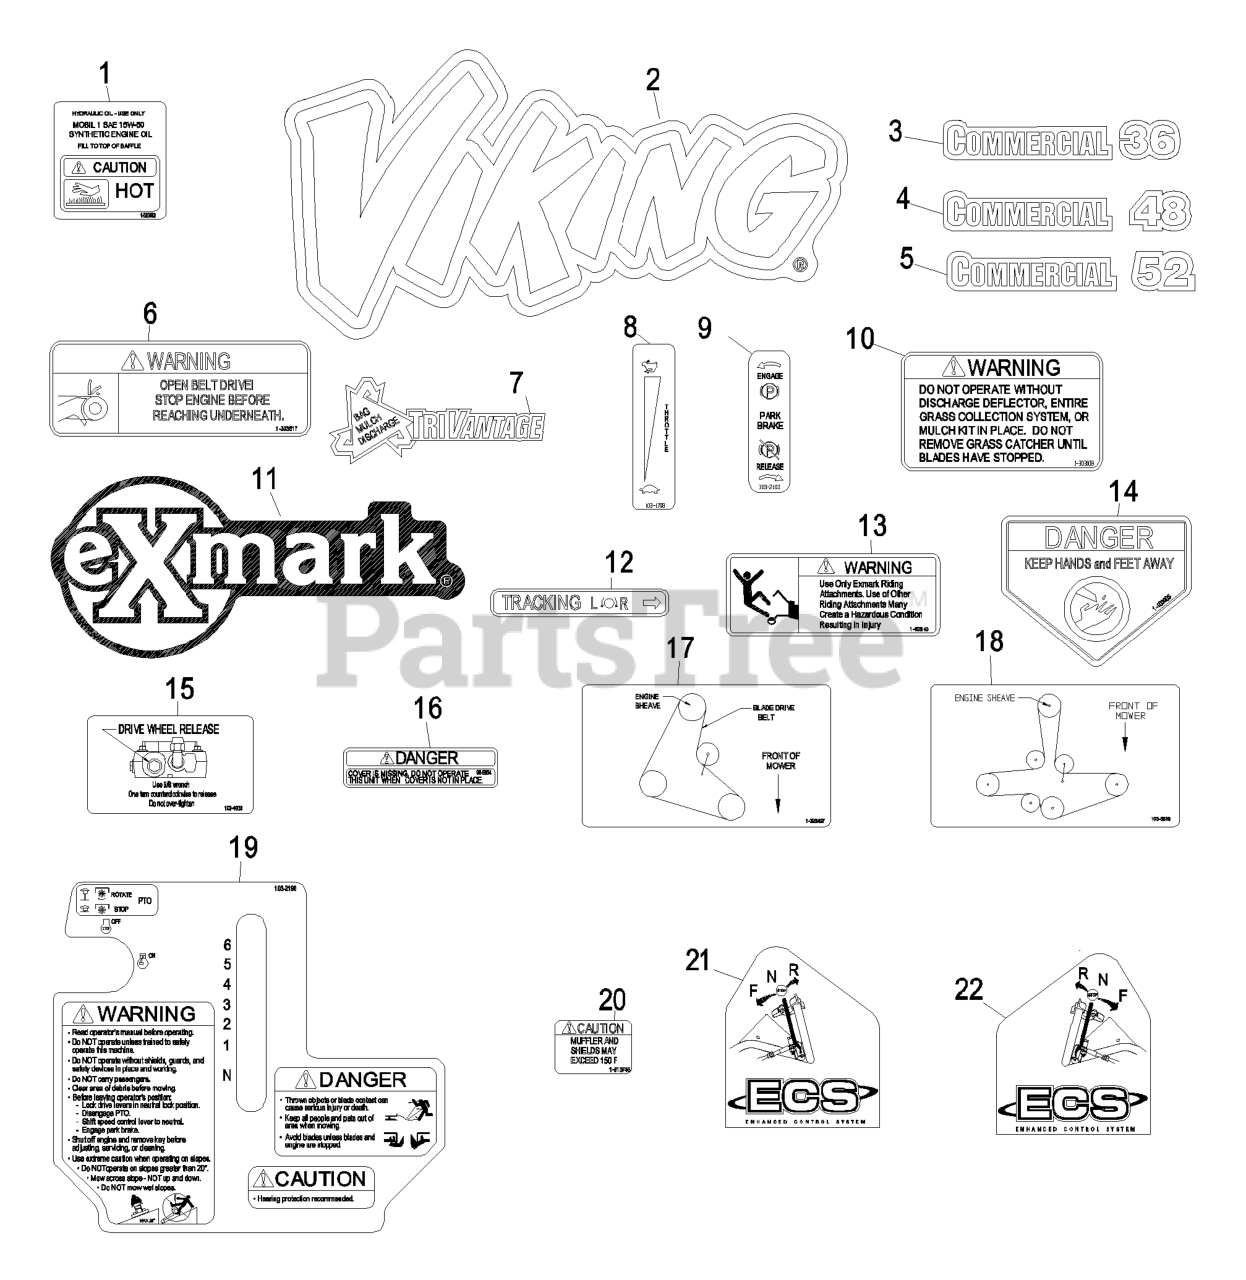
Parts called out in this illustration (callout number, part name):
2	DECAL,VH MODEL
3	DECAL,COMMERCIAL 36
4	DECAL,COMMERCIAL 48
5	DECAL,COMMERCIAL 52
6	DECAL,BELT DRIVE
8	DECAL,THROTTLE ONLY
9	DECAL-BRAKE, PARK
10	DECAL-WARNING, DISCHARGE
11	DECAL,EXMARK LOGO
12	DECAL,TRACKING ADJUST
13	DECAL,SULKY WARNING
14	DECAL-DANGER
15	DECAL,DRIVE RELEASE
16	DECAL-COVER, MISSING
17	DECAL,BELT ROUTING 32/36
18	DECAL,BELT ROUTING
19	DECAL,CONSOLE VH ECS
21	DECAL,LH ECS INSTRUCTION
22	DECAL,RH ECS INSTRUCTION
